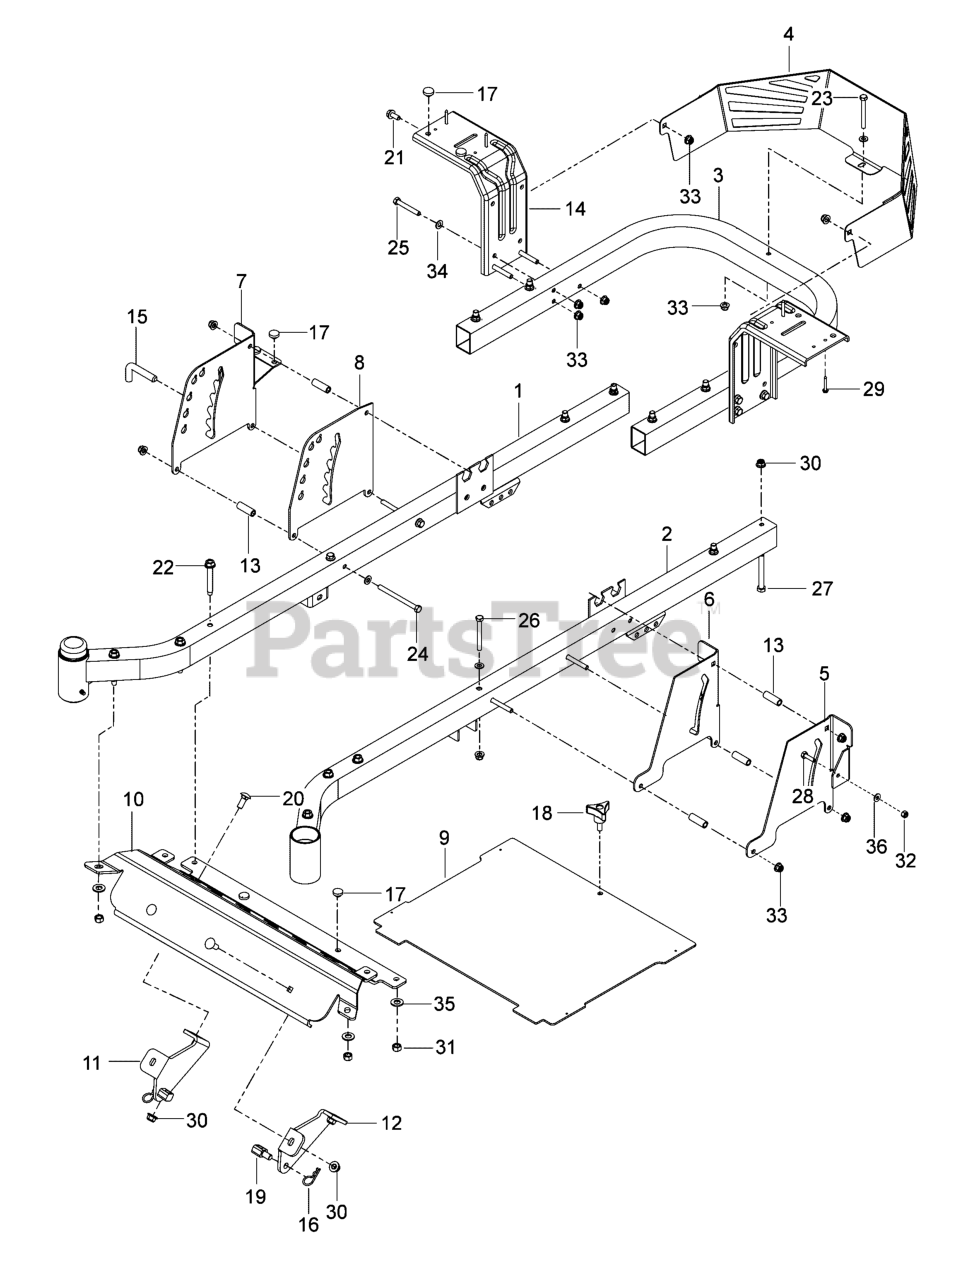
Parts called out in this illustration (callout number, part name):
1	FRAME, FRONT RIGHT
2	FRAME, FRONT LEFT
3	FRAME, REAR TUBE
5	BRACKET, Brake (outer)
6	BRACKET, Brake (Inner)
7	BRACKET, Height Adjust (Outer)
8	BRACKET, Height Adjust (Inner)
9	PLATE, Floor
10	FOOTREST
11	BRACKET, Support, RH, (Footrest)
12	BRACKET, Support, LH, (Footrest)
14	SUPPORT, Fender
15	PIN (Height Adjustment)
16	PIN, Retainer
19	TRUNNION (Footrest)
20	BOLT, 3/8-16 X 1 ROUND HD SQ NECK
21	BOLT, 5/16-18 X 3/4 GR. 5 ZD
22	CAPSCREW, 3/8-16 X 3 HEX FLANGE HD
23	BOLT, Hex Flange Head, 5/16-18 Gr 5
24	CAPSCREW, 5/16-18 X 4 HEX HD
25	CAPSCREW, 5/16-18 X 2-1/4 HEX HD
26	CAPSCREW, 5/16-18 X 2-3/4 HEX HEAD
27	CAPSCREW, 3/8-16 X 3 HEX HD
28	BOLT, Hex Fin, 1/4-20 UNC x 1 Gr 5
29	SCREW, #10-12 X 1-1/4
30	LOCKNUT, 3/8-16 HEX FLANGE NYLOC
31	LOCKNUT, 3/8-16 HEX JAM NYLOC
32	LOCKNUT, 1/4-20 HEX NYLOC
33	LOCKNUT, 5/16-18 HEX FLANGE NYLOC
34	WASHER, 11/32 x 11/16 x 16 Ga.
35	WASHER, FLAT, 3/8
36	WASHER, Flat, 1/4 SAE
